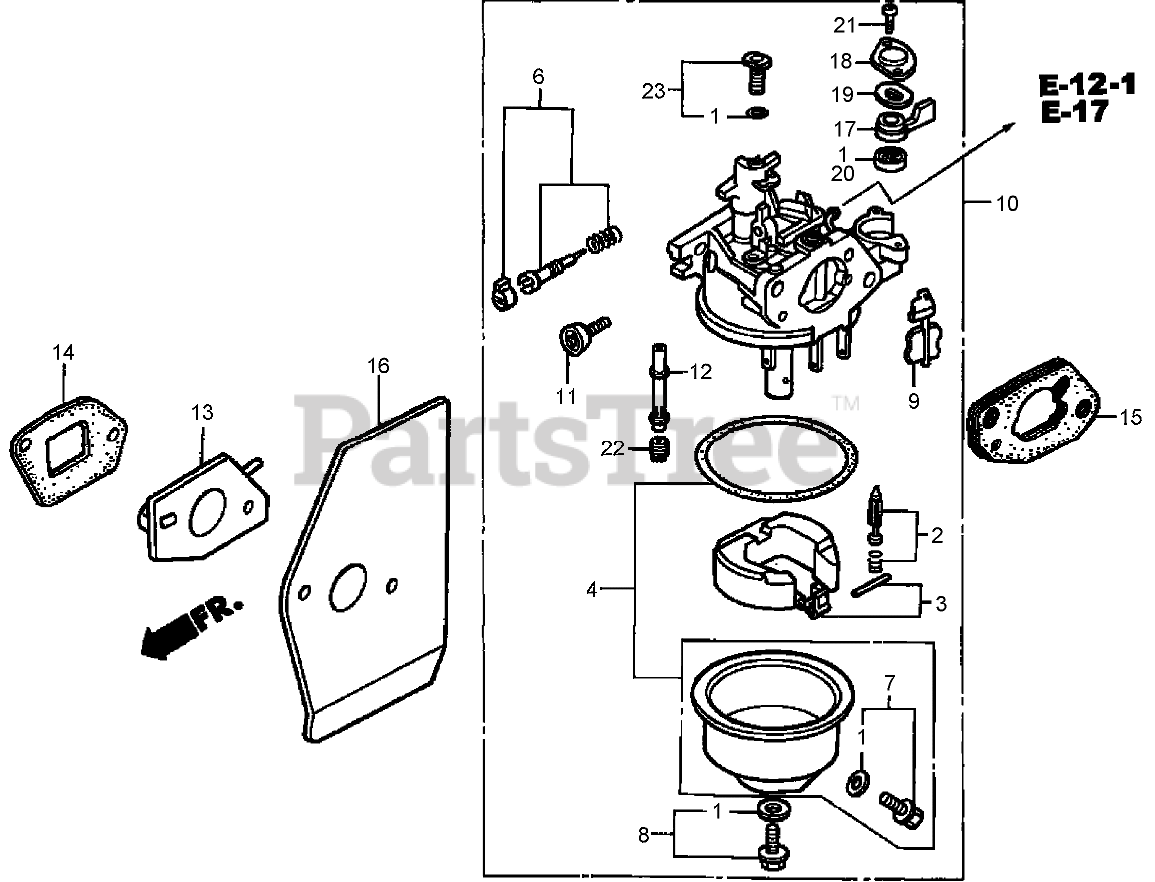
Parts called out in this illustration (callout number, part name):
1	GASKET SET
2	FLOAT VALVE SET
3	Float Set
4	FLOAT CHAMBER SET
6	PILOT SCREW SET
7	DRAIN SCREW SET
8	SCREW SET
9	Choke Set
10	CARBURETOR ASM
11	SCREW- STOP, THROTTLE
12	Nozzle-Main
13	Insulator-Carburetor
14	Gasket-Insulator
15	Spacer-Carburetor
16	Gasket-Carburetor
17	LEVER-PETCOCK
18	PLATE-SETTING, LEVER
19	SPRING-LEVER, PETCOCK
20	GASKET-PETCOCK
21	SCREW-PAN (3X6)
22	JET-MAIN (No. 60)
22	JET-MAIN (No. 62)
22	JET-MAIN (No. 65)
23	PILOT JET SET (No. 35)
